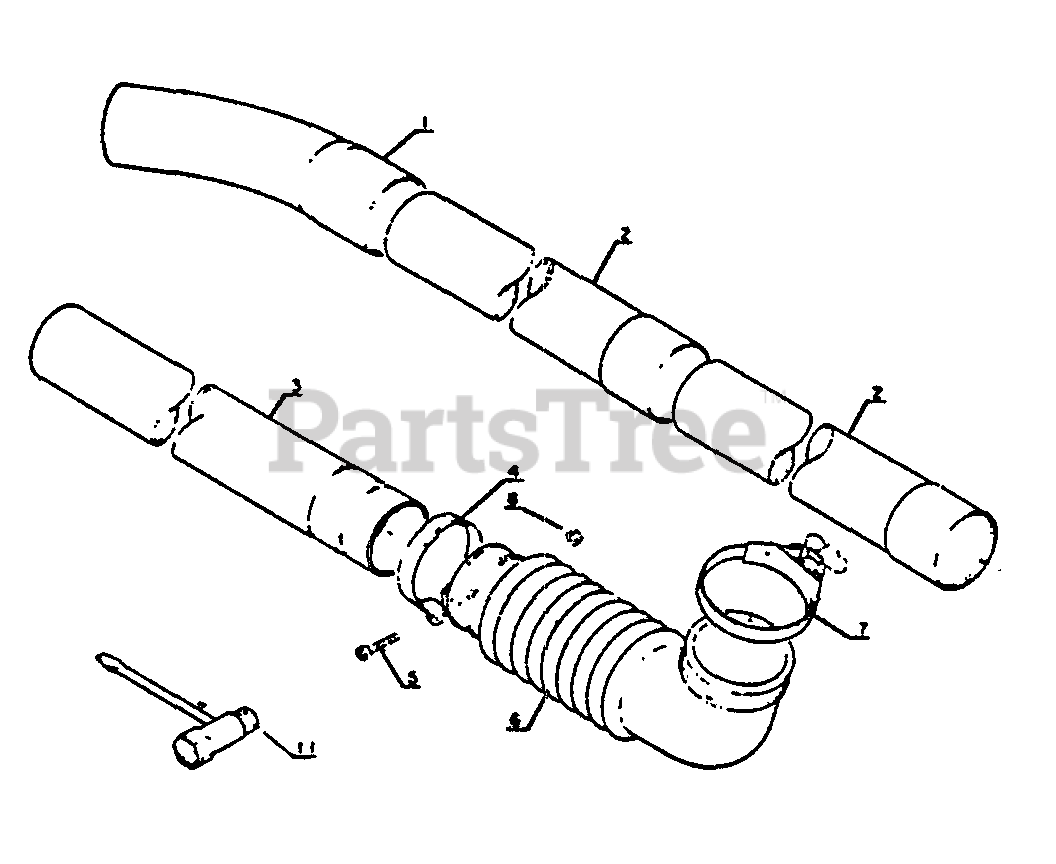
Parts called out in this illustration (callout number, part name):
1	TUBE, BLOWER - CURVED
2	TUBE, BLOWER - STRAIGHT
3	TUBE, BLOWER - STRAIGHT
4	CLAMP
5	SCREW 5×25
6	TUBE, BLOWER - FLEXIBLE
8	NUT M5
11	T-WRENCH 13×19×180
